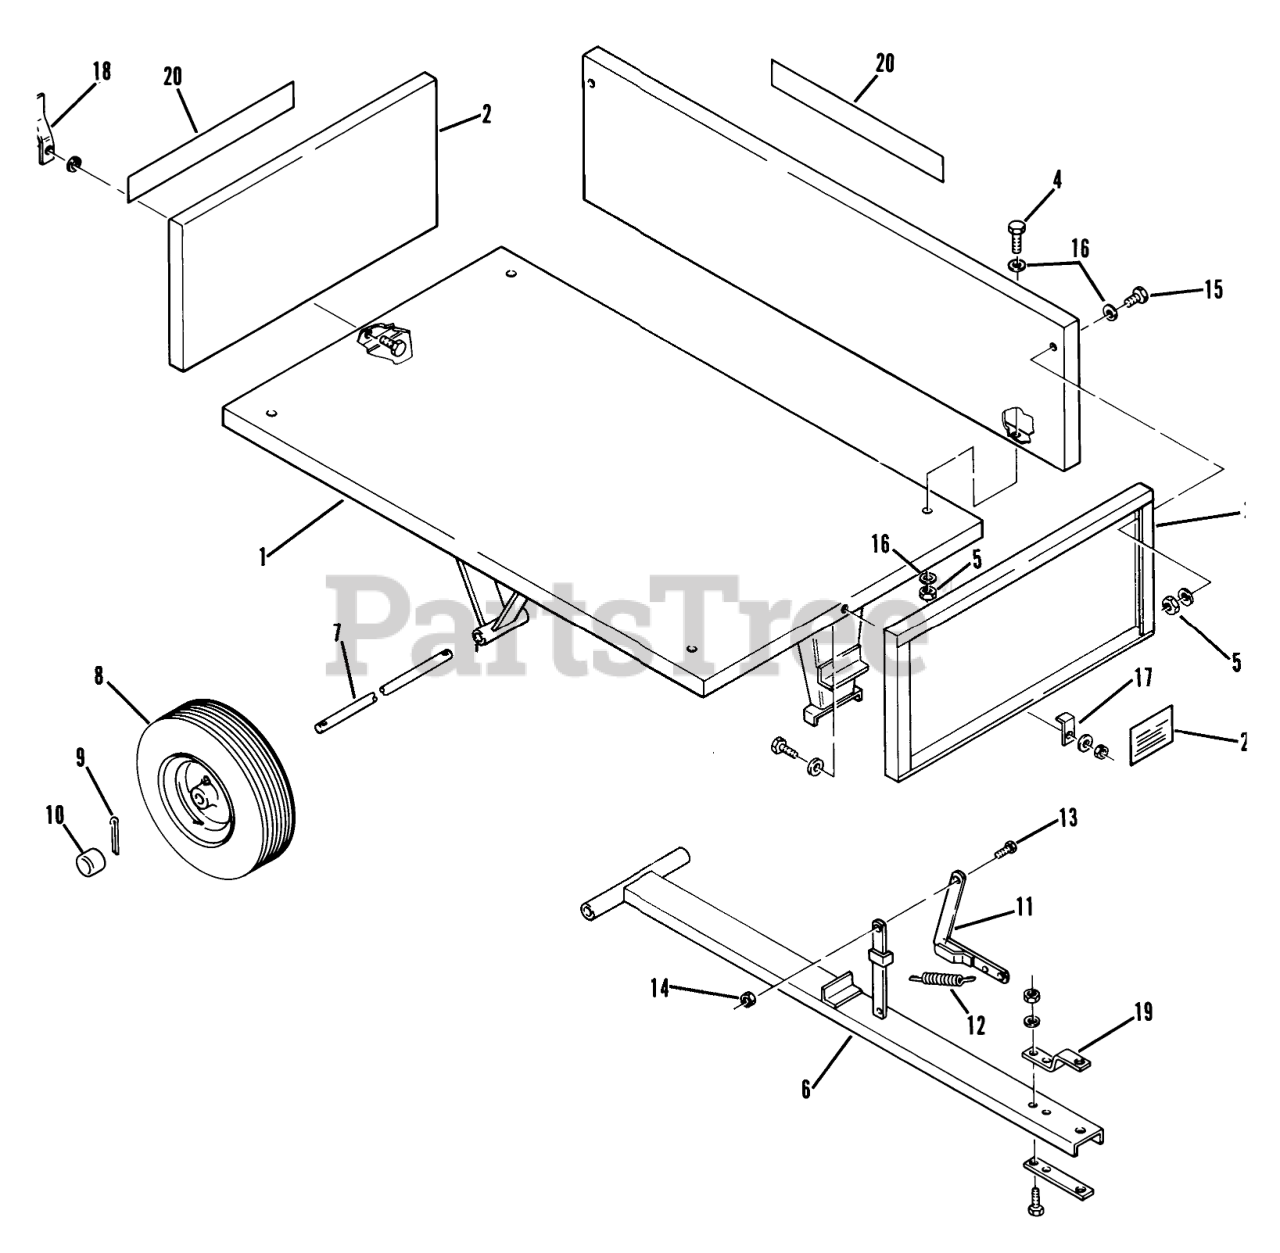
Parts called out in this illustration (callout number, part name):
1	Bed Assembly
2	Front and Rear Gate
3	Side Gate
4	BOLT
5	NUT
6	Drawbar Assembly
8	Wheel Assembly (6.50 x 8-16)
9	Cotter Pin
10	HUB CAP
11	Latch Assembly
12	SPRING
13	Bolt
14	Nut
15	Bolt
16	Washer
17	Latch-Front Gate
18	Latch-Rear Gate
19	CLEVIS-BAR
20	Decal
21	Decal,"Weight Limit"
